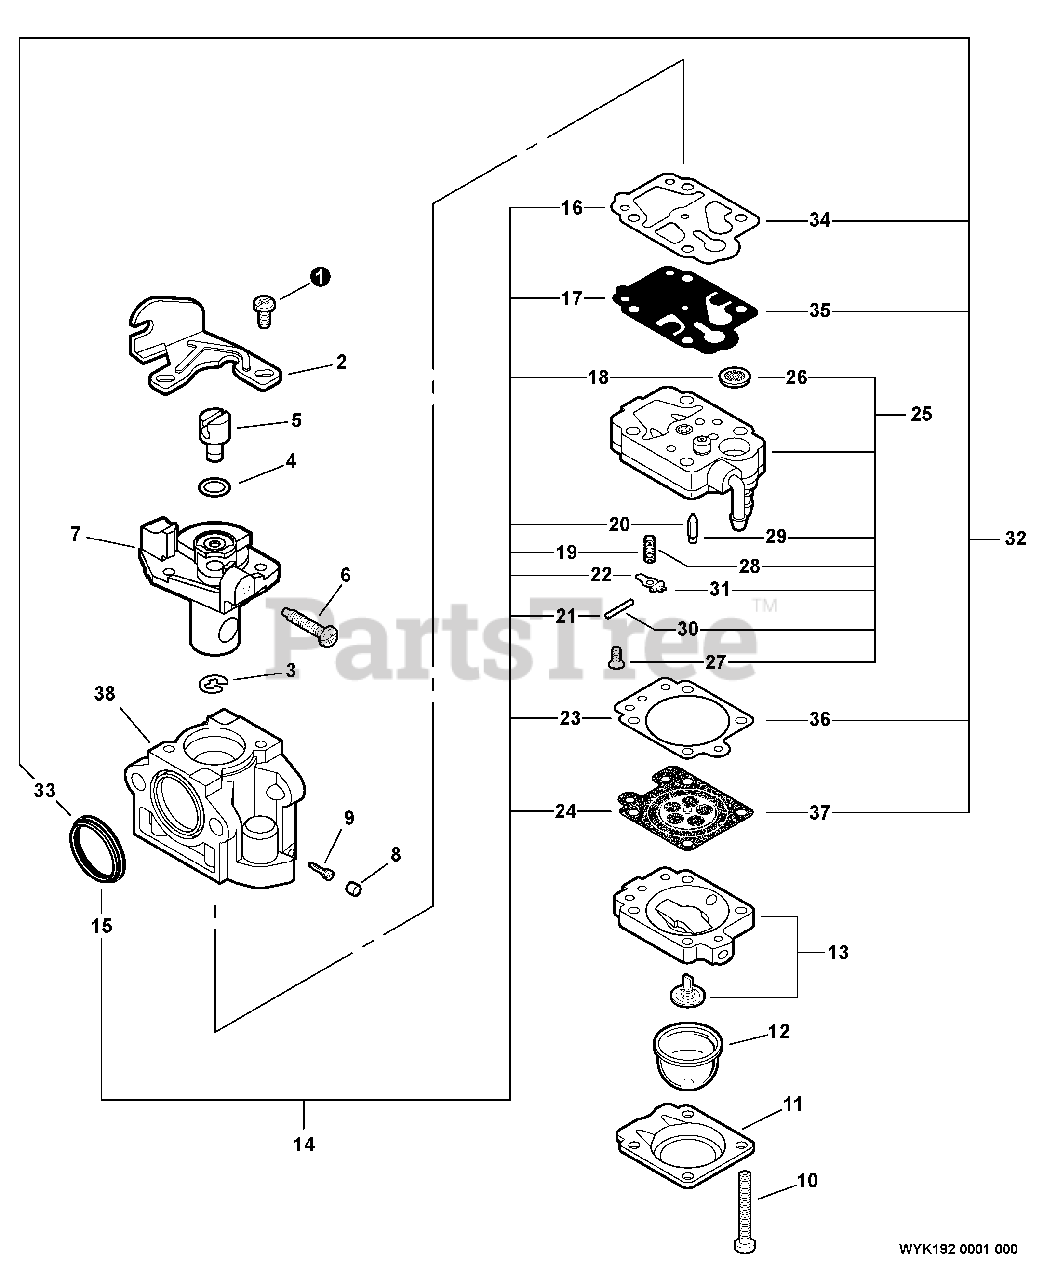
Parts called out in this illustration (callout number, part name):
2	BRACKET, CABLE
3	RING, RETAINING
6	SCREW, IDLE ADJUST
7	THROTTLE VALVE ASSY
8	CAP, LIMITER
9	NEEDLE - HIGH SPEED
10	SCREW, PUMP COVER
11	RETAINER, PURGE BULB
12	BULB, PURGE
13	PURGE BASE ASSY
14	REPAIR KIT
15	SEAL
16	GASKET, PUMP
17	DIAPHRAGM, PUMP
18	STRAINER
19	SPRING, METERING LEVER
20	VALVE, INLET NEEDLE
21	PIN, METERING LEVER
22	LEVER, METERING
23	GASKET, DIAPHRAGM
24	DIAPHRAGM, METERING
25	PUMP BODY ASSY
26	STRAINER
27	SCREW, METERING LEVER PIN
28	SPRING, METERING LEVER
29	VALVE, INLET NEEDLE
30	PIN, METERING LEVER
31	LEVER, METERING
32	DIAPHRAGM/GASKET KIT
33	SEAL
34	GASKET, PUMP
35	DIAPHRAGM, PUMP
36	GASKET, DIAPHRAGM
37	DIAPHRAGM, METERING
38	BODY, CARBURETOR
